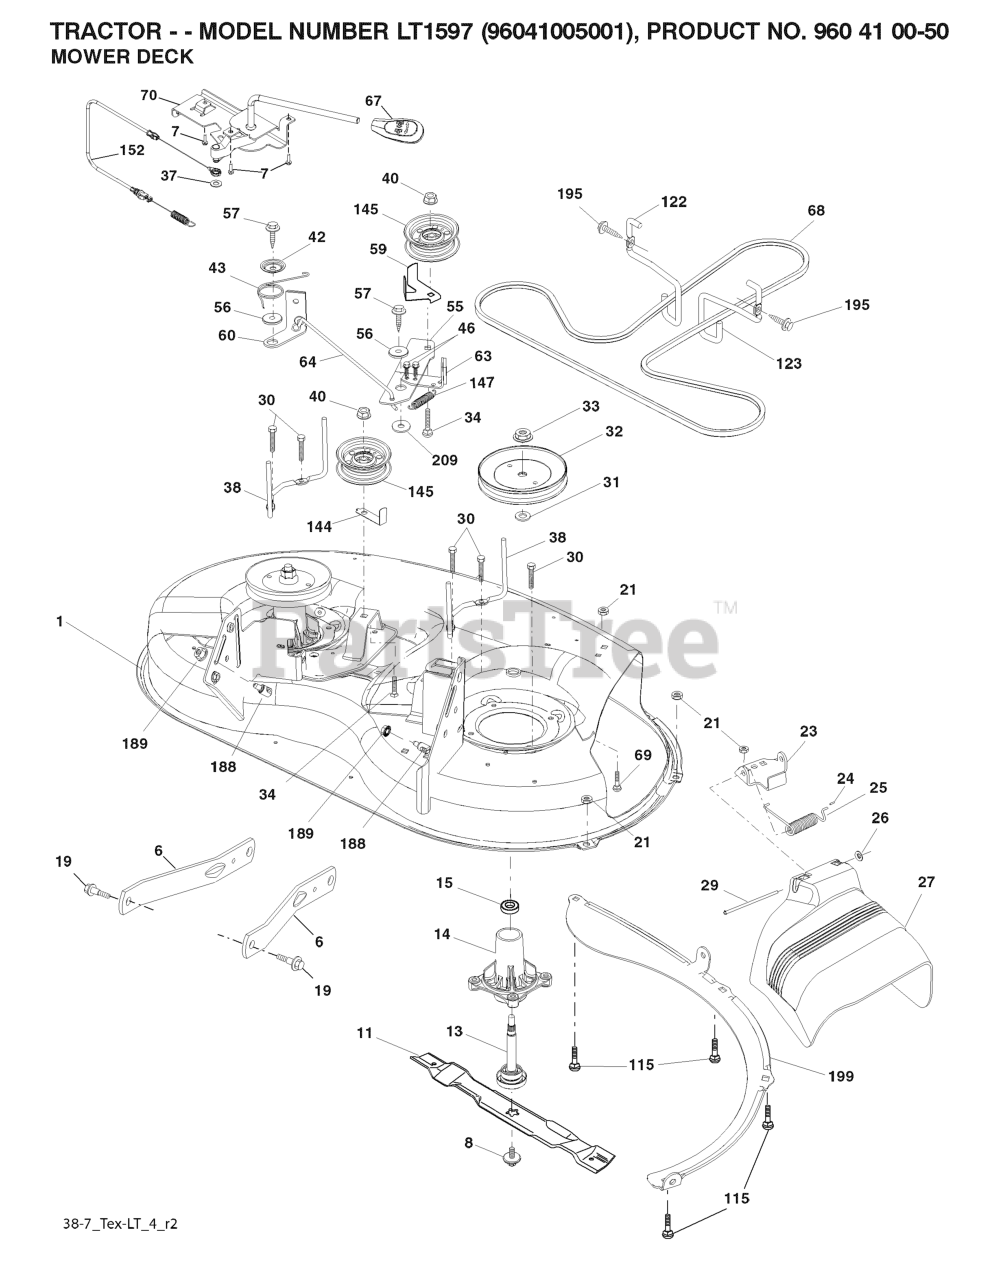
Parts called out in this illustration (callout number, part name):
1	PLATE.ENGINE.PNT.23"FRAME.EDIP
2	CLUTCH.105.FT-LBS
3	EXHAUST.TUBE.LH.BS/TWIN
4	EXHAUST.TUBE.RH.B&S.TWIN.INTEK
5	BRACKET MUFFLER MS431BLK
6	ARM IDLER
7	SPINDLE.IDLER
8	PULLEY.ENGINE
9	PULLEY, IDLER RAKE & ZTR
10	T & B SPACER
11	STOP, CLUTCH, BLACK
12	GUARD.MUFFLER.WO.TOW.HITCHX431
13	MUFFLER ASM TWIN
14	SPRING, DECK DRIVE
15	GASKET.MUFFLER
16	HEAT SHIELD
17	BEARING.FLANGED.PLASTIC.3/4ID
18	BOLT.FLANGE.1/2-13 X 2.75.GRD5
19	HCS 3/8-16X3-1/2 TAPBLT GR5 ZD
20	RHSNB 5/16C X 1
21	RP BOLT 5/16-18 X3/4 ZN/YEL GR
22	CLUTCH BOLT7/16-20X3.5 GR524HR
23	SCREW 3/8-16X1
24	SCREW.SOCKET.HEAD.5/16-18
25	SCREW.THDROL.5/16-18X3/4.TTY
26	NUT, 1/2-13 HEX FLG NYLOC ZD
27	5/16-18 NYLOC FLANGE NUT
28	NUT 3/8-16 NYLOC
30	WASHER 5/16 FLAT
